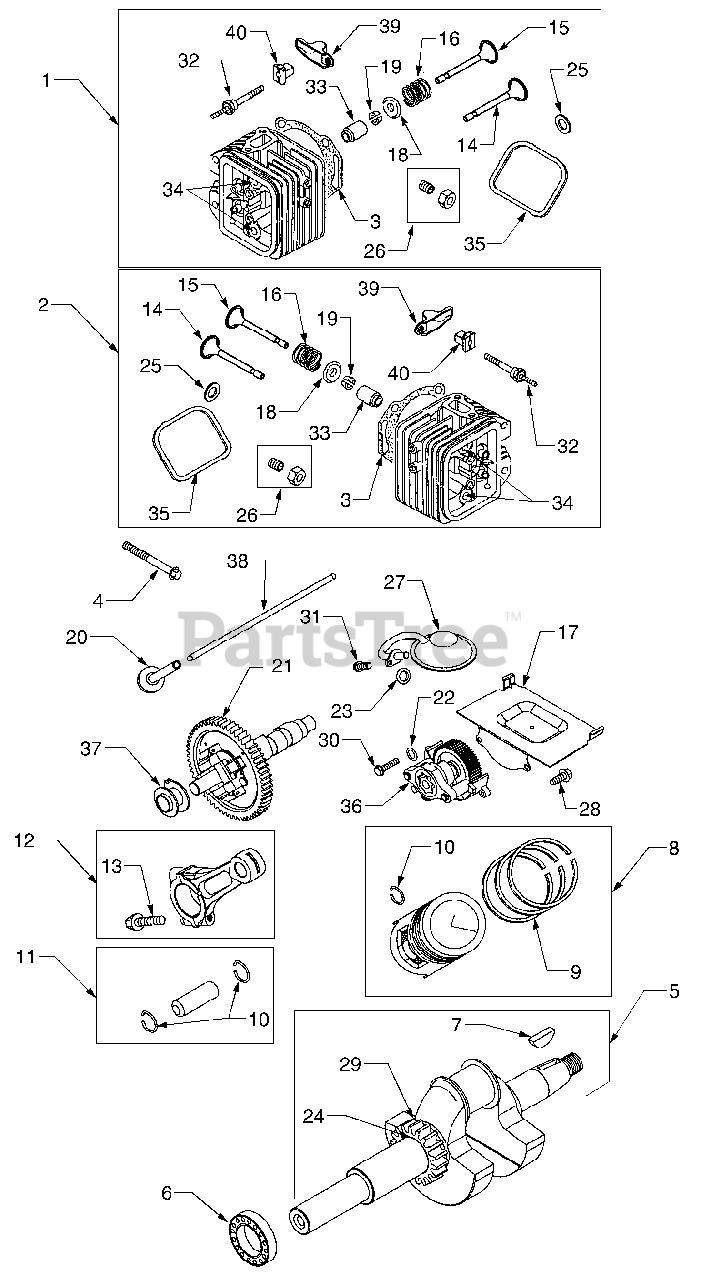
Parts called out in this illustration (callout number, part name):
1	Head, Cylinder #1
2	Head, Cylinder #2
3	Gasket, Cylinder Head
4	Screw, Cylinder Head
5	Crankshaft
6	Bearing, Ball
7	Key, Flywheel
8	Piston Assembly (Standard)
9	Ring Set, Piston (Standard)
10	Lock, Piston Pin
11	Pin Assembly, Piston
12	Rod Assembly, Connecting
13	Screw, Connecting Rod
14	Valve, Exhaust
15	Valve, Intake
16	Spring, Valve
17	Deflector, Oil
18	Retainer, Valve Spring
19	Retainer, Valve (2)
20	Tappet, Valve
21	Gear, Cam
22	Seal, O-Ring
23	Seal, O-Ring
24	Key, Timing
25	Washer
26	Screw, Valve Adjustment
27	Screen, Oil Pump
28	Screw, Hex
29	Gear, Timing
30	Screw, Hex
31	Screw, Hex
32	Stud, Rocker Arm
33	Seal, Guide Bushing
34	Bushing, Guide
35	Gasket, Rocker Cover
37	Spool, Governor
38	Push Rod, Intake
39	Rocker Arm
40	Pivot, Rocker Arm
